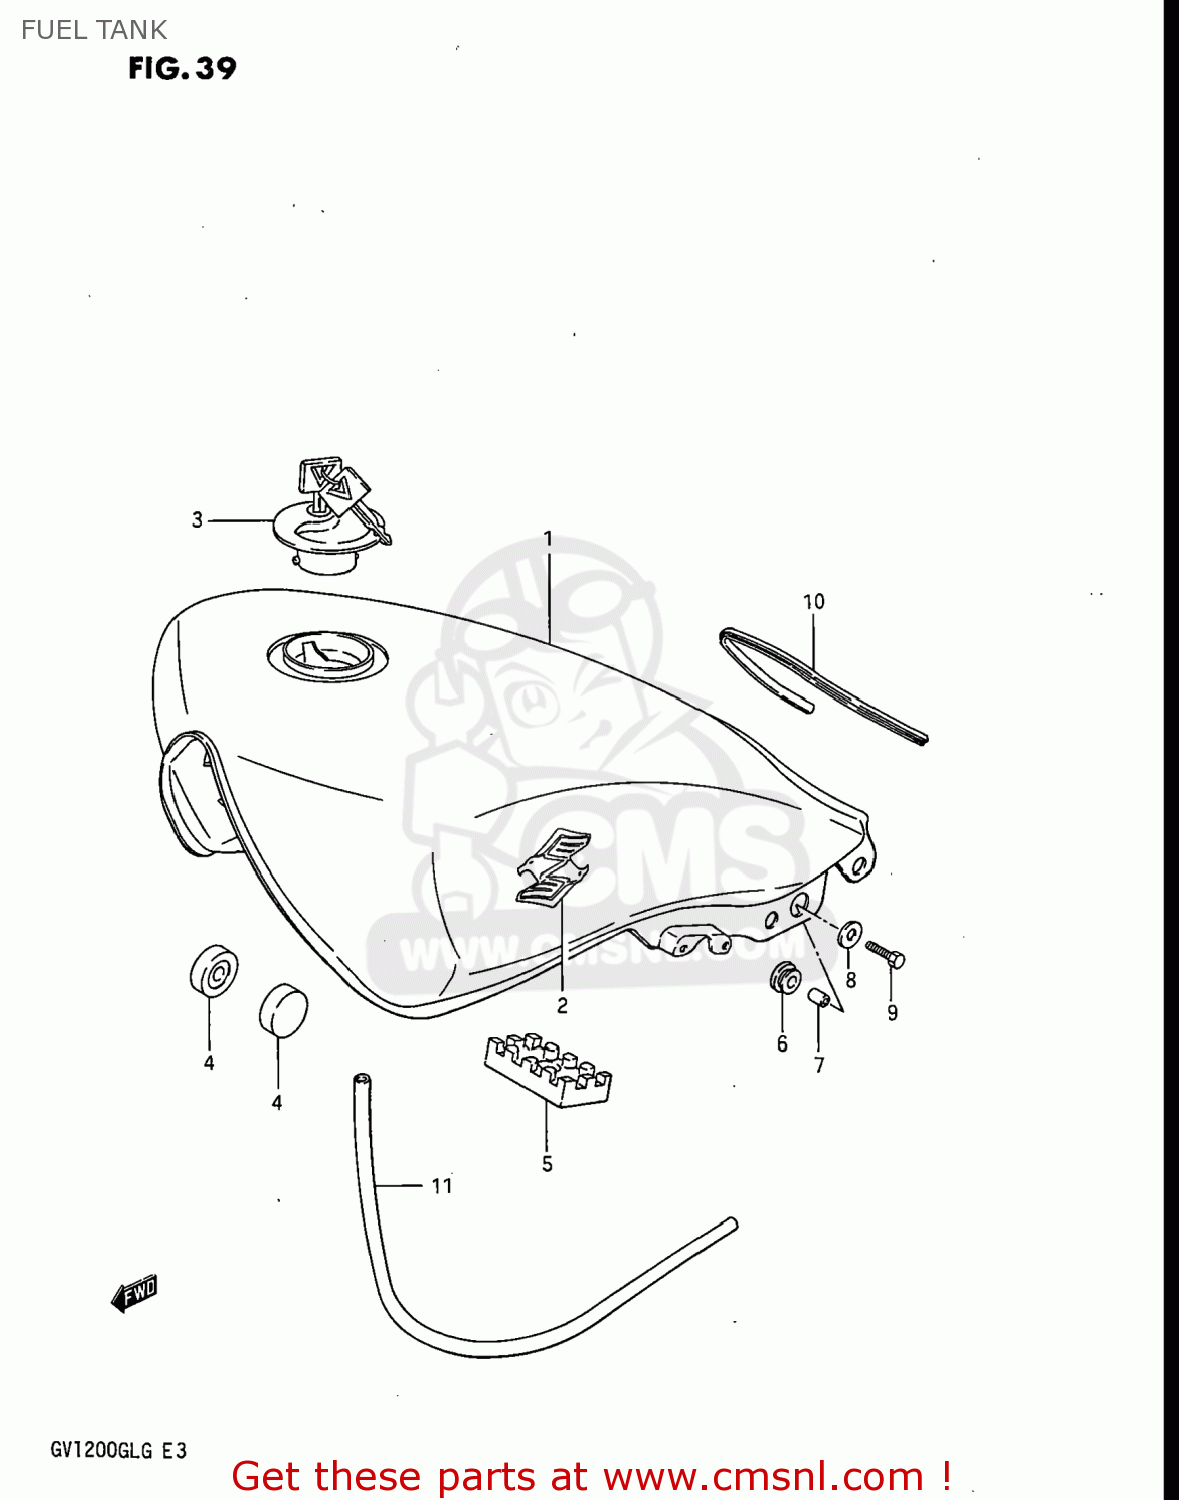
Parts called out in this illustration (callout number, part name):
1	TANK ASSEMBLY,FUEL
2	EMBLEM
3	CAP SET,FUEL TANK
4	CUSHION
5	CUSHION,FUEL TANK CTR
6	CUSHION
7	SPACER (6.8X10X10)
8	WASHER (6.5X24X1.6)
9	BOLT
11	HOSE
